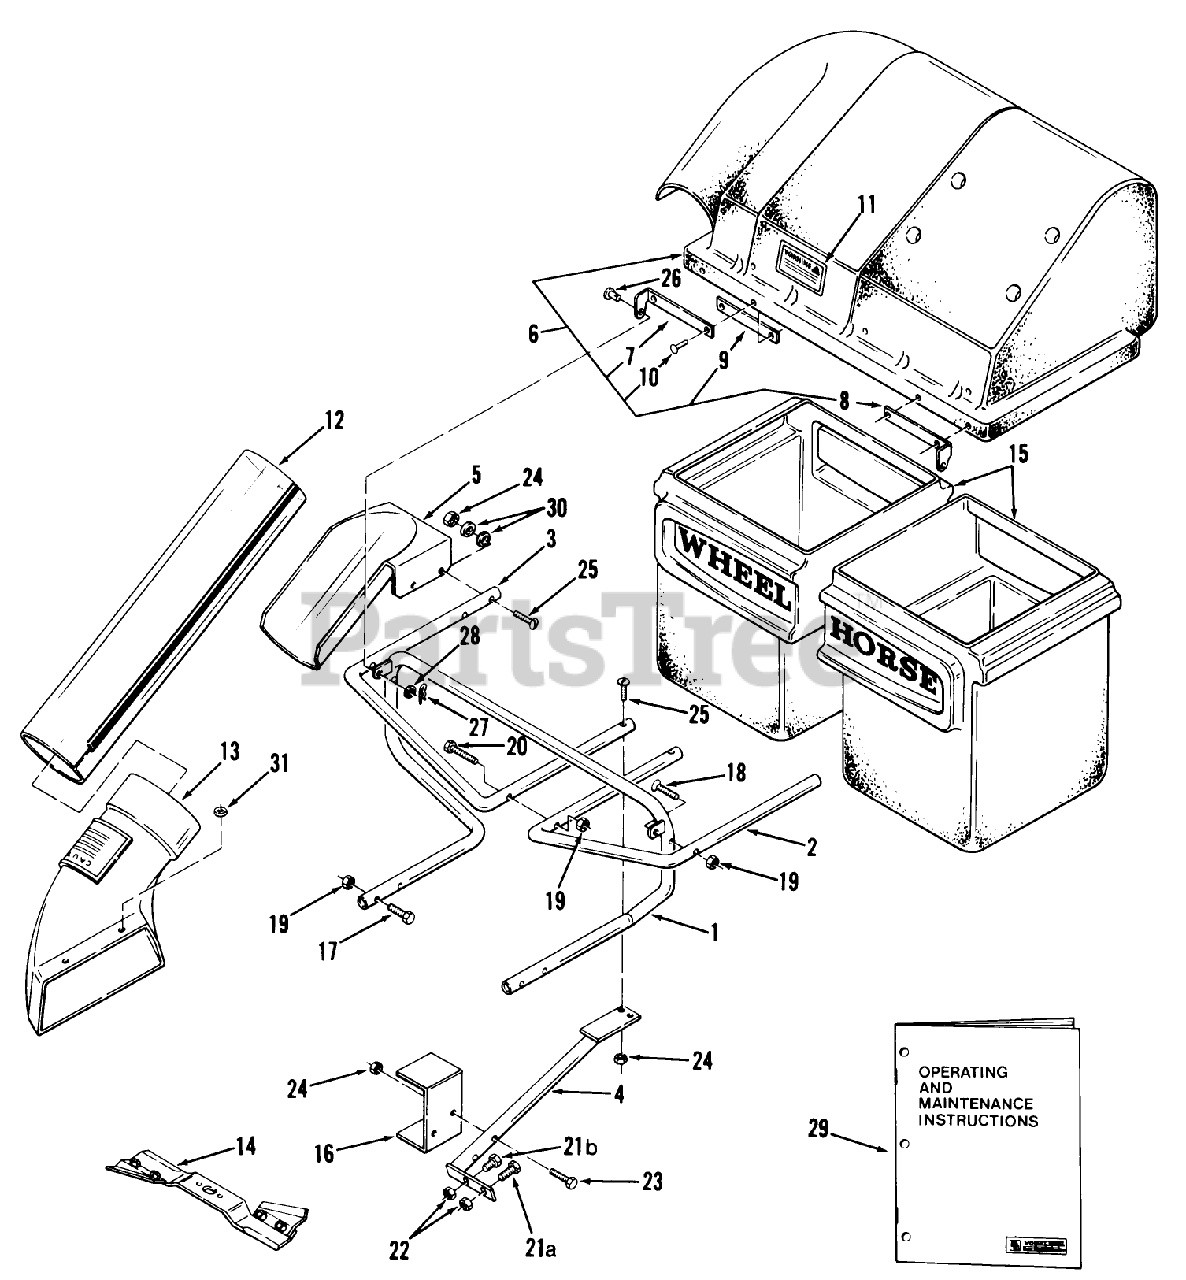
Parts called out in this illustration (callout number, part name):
5	SUPPORT-COLLECTOR TB
11	Warning Decal
18	Screw Flat Hd. Mach. 5/16 x 2 1/2
19	Eslok Nut 5/16-18
26	PIN
27	Hairpin Cotter
29	Operating and Maintenance Instructions
